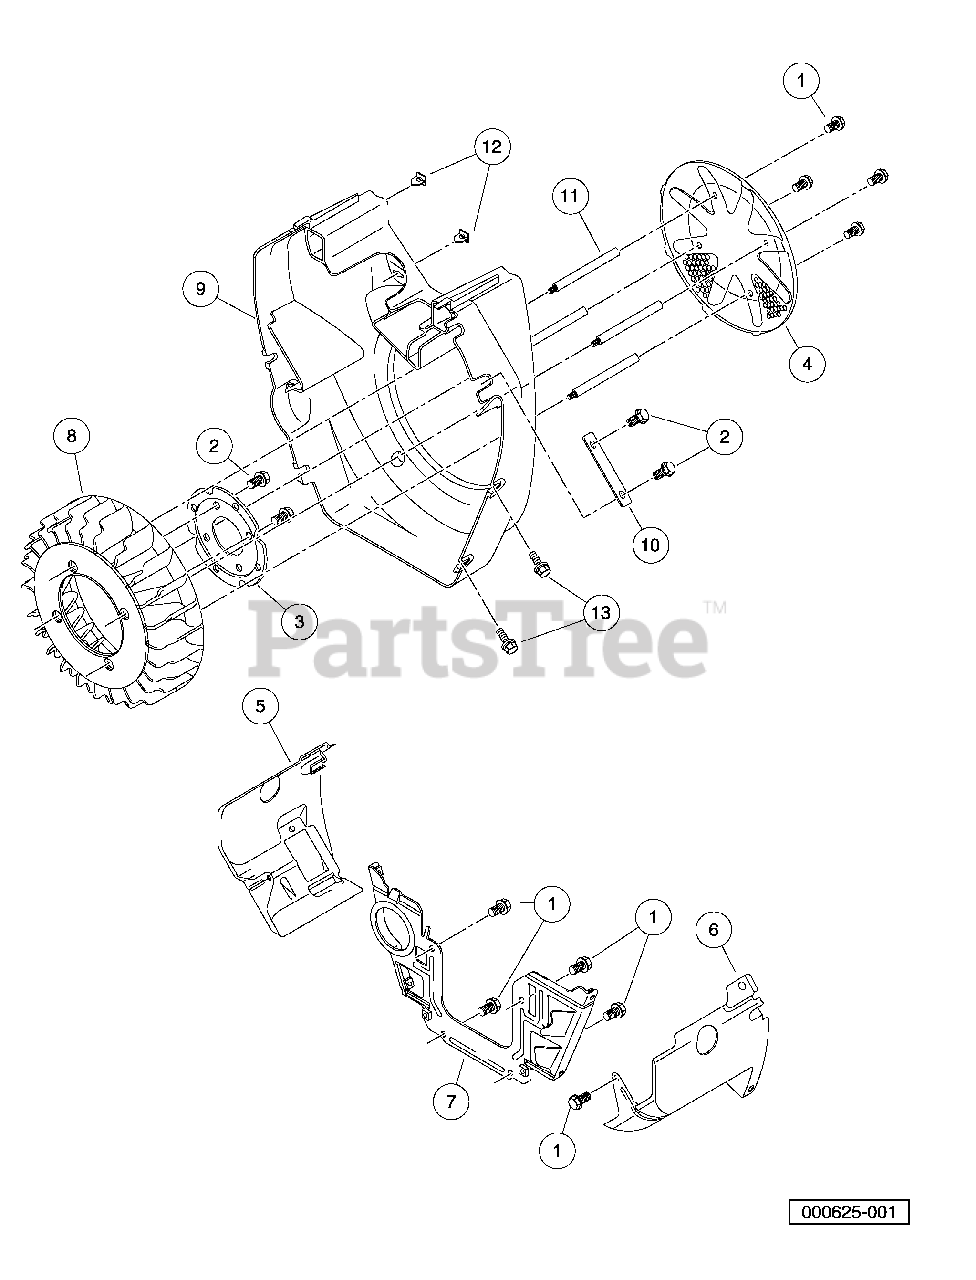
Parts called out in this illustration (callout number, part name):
1	Bolt, Flg, M6 X 1.0 X 12
2	Bolt, Flg, M6 X 1.0 X 16
3	Plate, Housing, Fan, Fh
4	Screen, Fan, Fh.
5	Shroud, Engine, Rh, Fh
6	Shroud, Engine, Lh, Fh
7	Shroud, Engine, Front, Fh
8	Fan, Cooling, Fh
9	Housing, Engine, Fh
10	Washer, Housing, Fan, Fh
11	Stud, Fan Screen, Fh
12	Nut, Press In, Front Cover, Fh
13	Bolt, Oil Pickup, Fh
